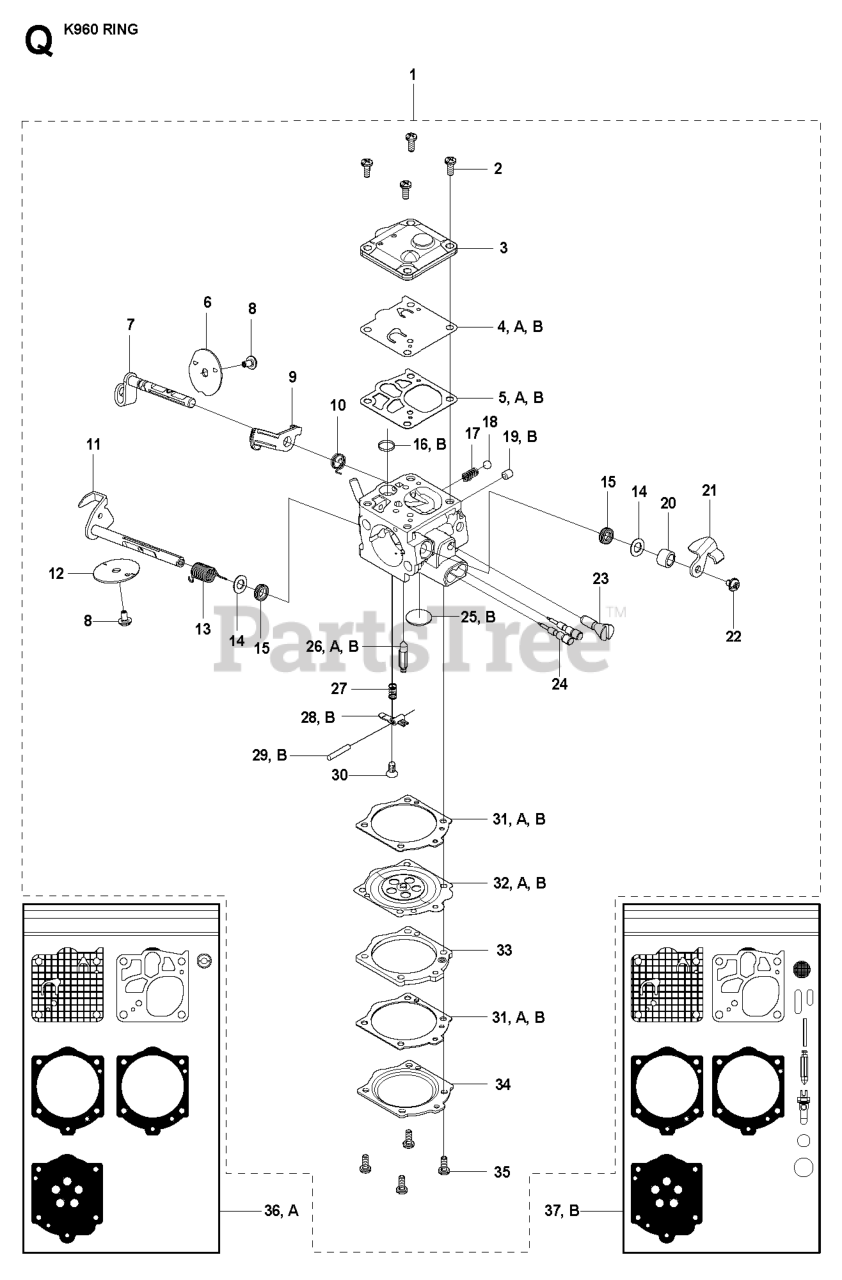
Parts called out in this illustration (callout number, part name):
1	CARBURETOR ASSY RWJ-3
2	SCREW W/ WASHER
3	COVER
4	DIAPHRAM PUMP
5	GASKET
7	SHAFT CHOKE ASSY
10	SPRING FAST IDLE RETURN
11	SHAFT, THROTTLE ASSY
16	FUEL INLET SCREEN
19	PLUG
25	WELCH PLUG
26	VALVE INLET NEEDLE
27	SPRING-METER.LEVER
28	LEVER
29	PIN
31	GASKET
32	DIAPHRAM PUMP
36	GASKET KIT
37	REPAIR KIT
